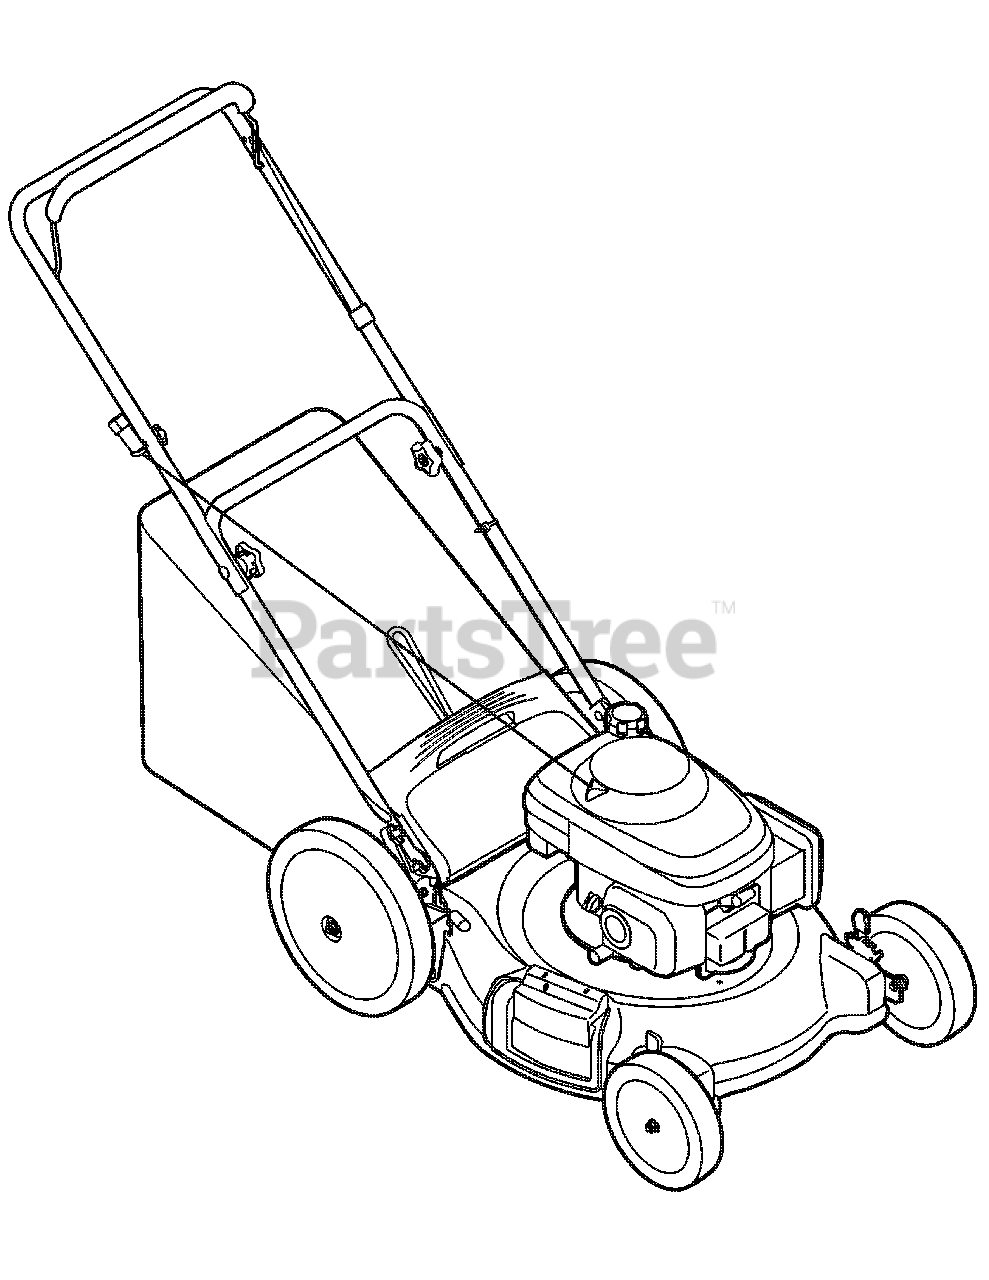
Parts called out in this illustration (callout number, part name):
NA	Pre-Filter
NA	Drive Belt
NA	Drive Cable
NA	Ignition Key
